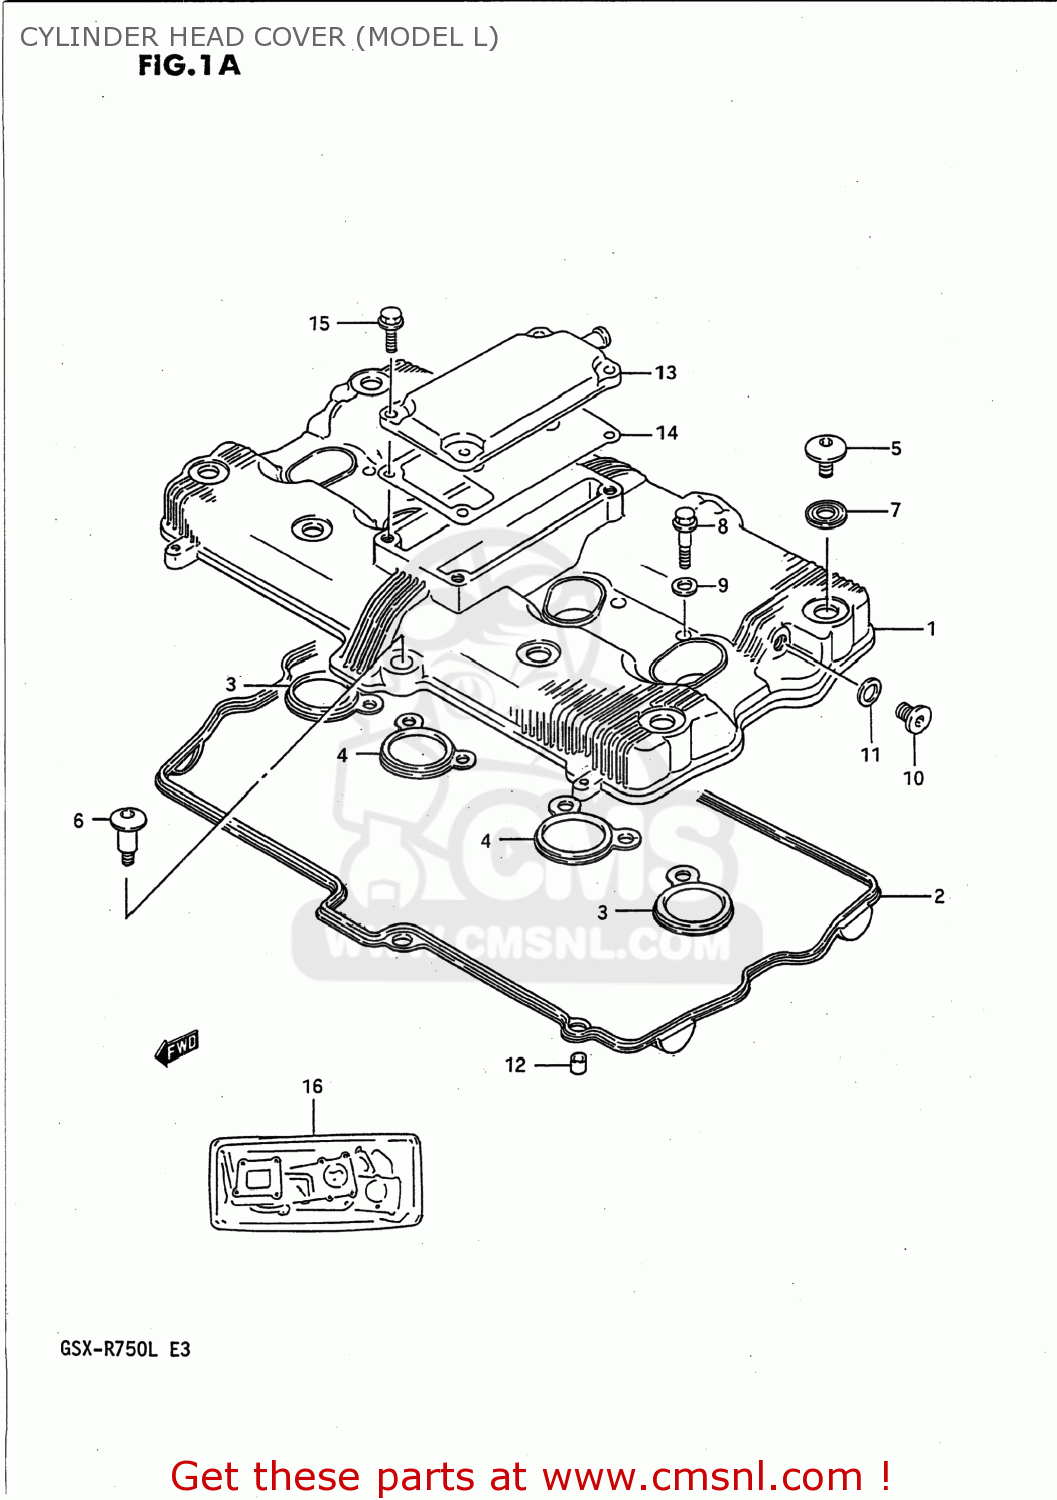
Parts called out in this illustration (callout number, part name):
1	COVER,CYLINDER HEAD
2	GASKET,CYLINDER HEAD COVER (NAS)
3	GASKET,HEAD COVER NO.2 (NAS)
4	GASKET,HEAD COVER NO.3 (NAS)
5	BOLT(7X17.5)
6	BOLT(7X31)
7	WASHER
8	BOLT,UNION 8X35
9	GASKET 8.2X14X1 (NAS)
10	PLUG(L:12)
11	GASKET(12.1X16.2X3.7) (NAS)
12	PIN
13	COVER,BREATHER
14	GASKET (NAS)
15	BOLT
16	GASKET SET
